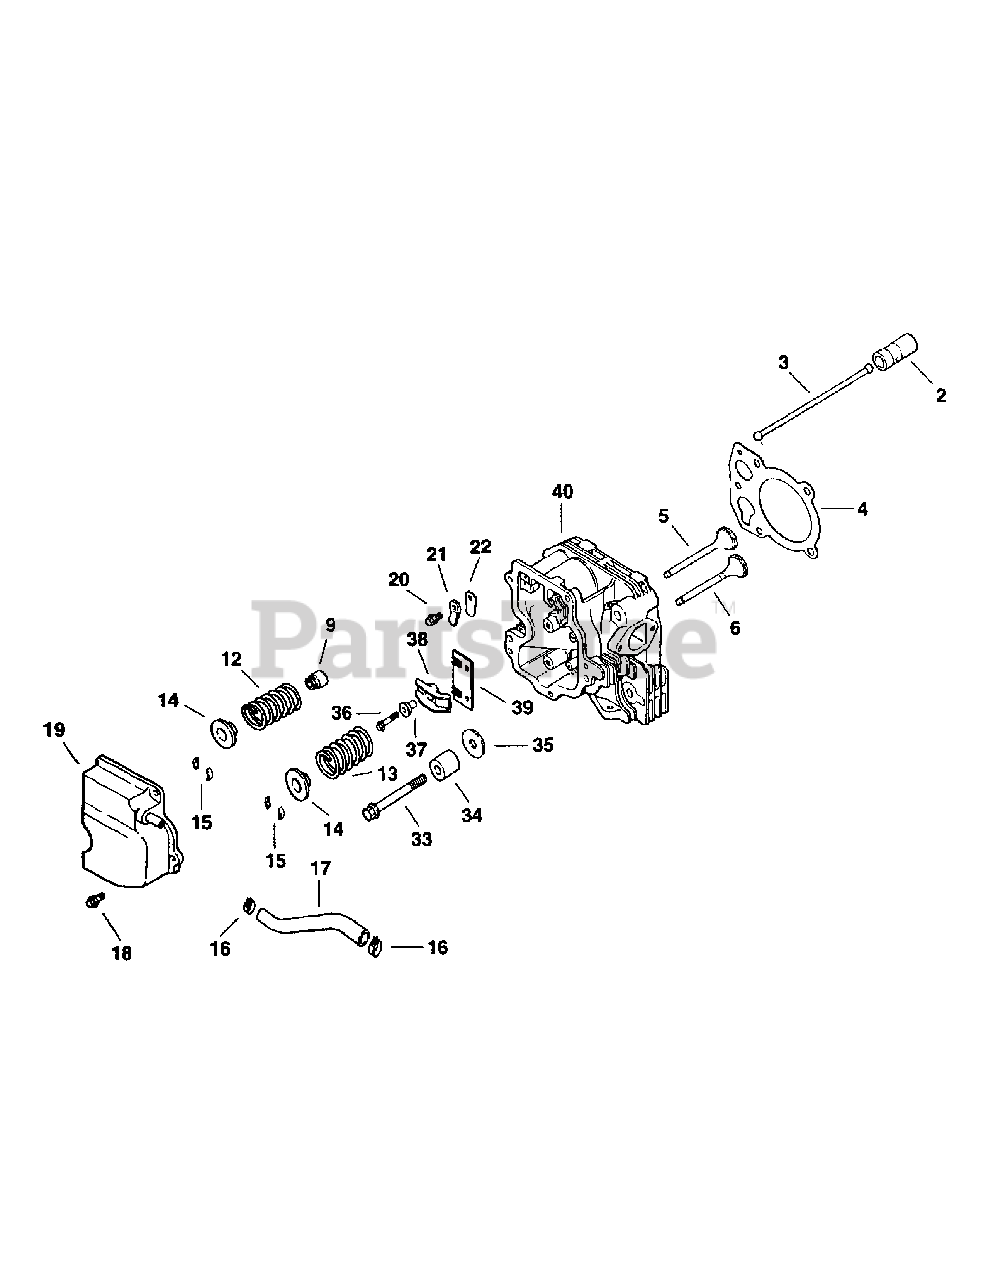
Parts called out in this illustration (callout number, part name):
2	Lifter, Valve
3	Rod, Push
4	Gasket, Cylinder Head
5	Valve, Intake (Std.)
5	Valve, Intake (.25 o.s.)
6	Valve, Exhaust (Std.)
6	Valve, Exhaust (.25 o.s.)
9	Seal, Valve Stem
12	Spring, Intake Valve
13	Spring, Exhaust Valve
14	Cap, Valve Spring
15	Retainer Kit
16	Clamp, Hose
17	Hose, Breather
18	Screw, Hex Flange
19	Cover, Valve w/Nipple
20	Screw, Hex Flange
21	Retainer, Breather Reed
22	Reed, Breather
33	Screw, Hex Flange
34	Spacer, Head Bolt Exhaust Port
35	Washer, Plain 13/32"
36	Screw, Hex Flange
37	Pivot, Rocker Arm Kit
38	Arm, Rocker
39	Plate, Guide
40	Head, Cylinder
